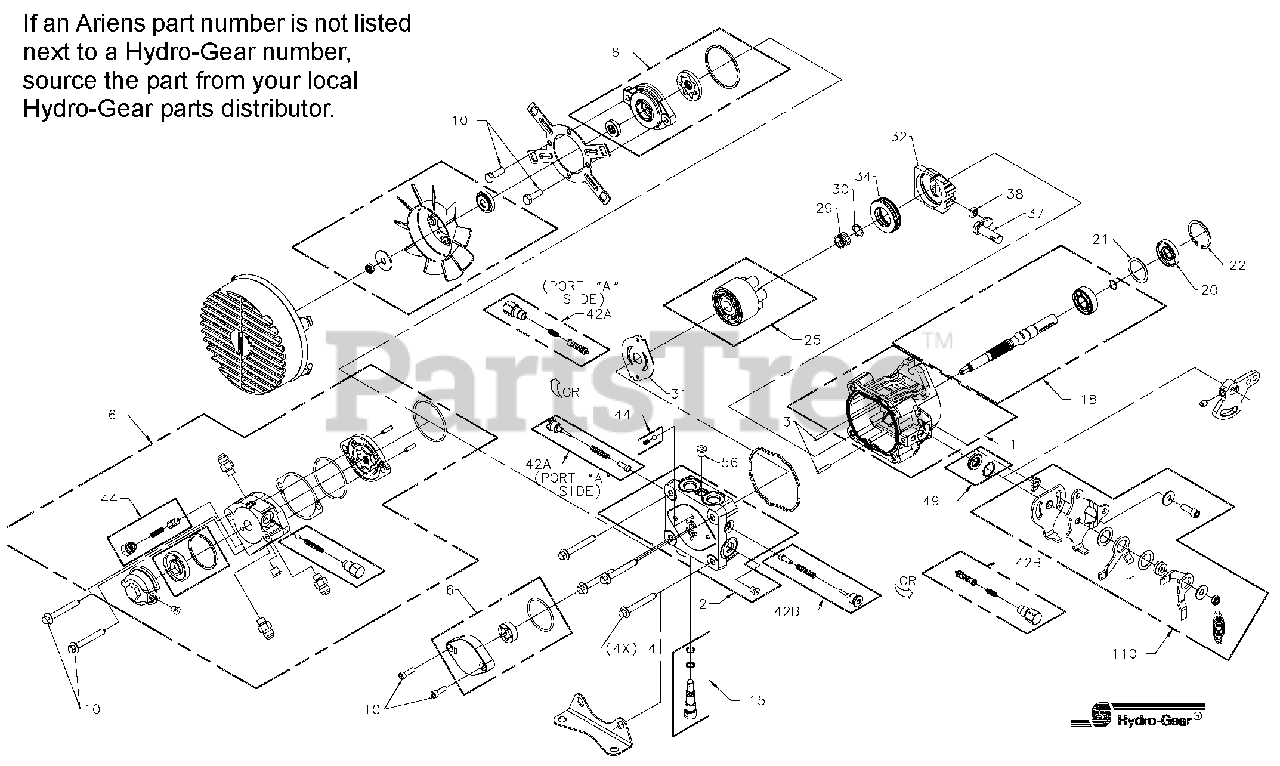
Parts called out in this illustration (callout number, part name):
1	KIT, HSG
2	KIT, ENDCAP STD CHG W/PPT
3	PIN, .219X1
4	HFHCS M8X60
6	KIT, CHG PUMP STD CHG, TH
10	HHCS 5/16-18X1
15	KIT, BYPASS VALVE
18	KIT, PUMP SHAFT
20	SEAL, LIP 17X40X7
21	WASHER 1.23X1.56X.04
22	RING, RET 1.56 INT
25	KIT, 10 CC BLOCK
29	SPRING. BLOCK
30	WASHER. THRUST .59 X .79 X .04
31	PLATE, VALVE
32	SWASHPLATE. VARIABLE
34	BEARING. THRUST 30 X 52 X 13
37	ARM. TRUNNION TAPERED SQUARE
38	GUIDE. SLOT
42	KIT, SHOCK VALVE 200 BAR
44	KIT, CHG RELIEF
49	KIT, PUMP SEAL
56	PLUG 7/16-20 (METAL)
110	RETURN KIT
NS	KIT, PUMP SEAL
